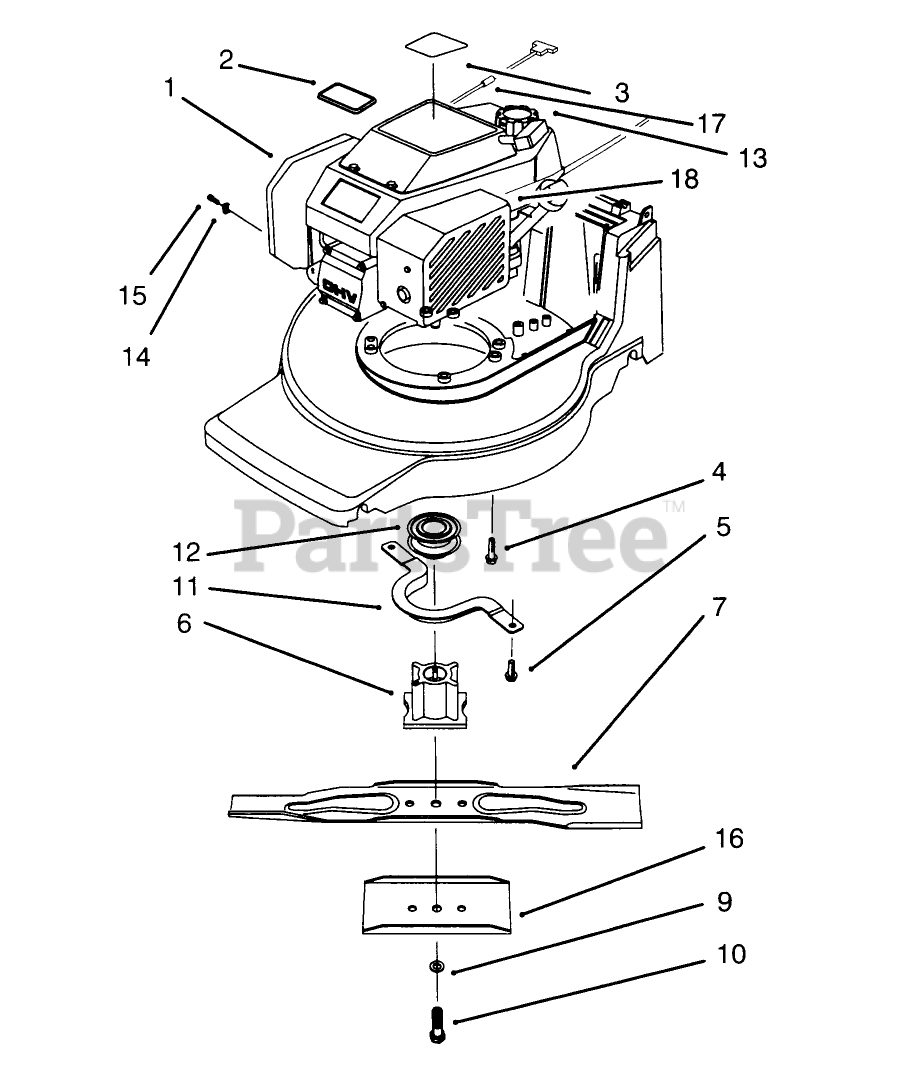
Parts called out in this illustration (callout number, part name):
1	Engine
2	PLATE-LOGO
3	DECAL - ENGINE
4	SCREW-HWH
5	SCREW-HWH
6	BLADE RETAINER - 25 MM
7	Blade
9	WASHER-LOCK
10	BOLT-BLADE
11	Guide-Belt
12	PULLEY-DRIVE, ZONE START
13	ASSY FUEL CAP
14	CLAMP-CASING
15	CLAMP SCREW F/W ENGINE
16	Stiffener
17	STOP-ROPE
18	COVER - BRAKE F/W
